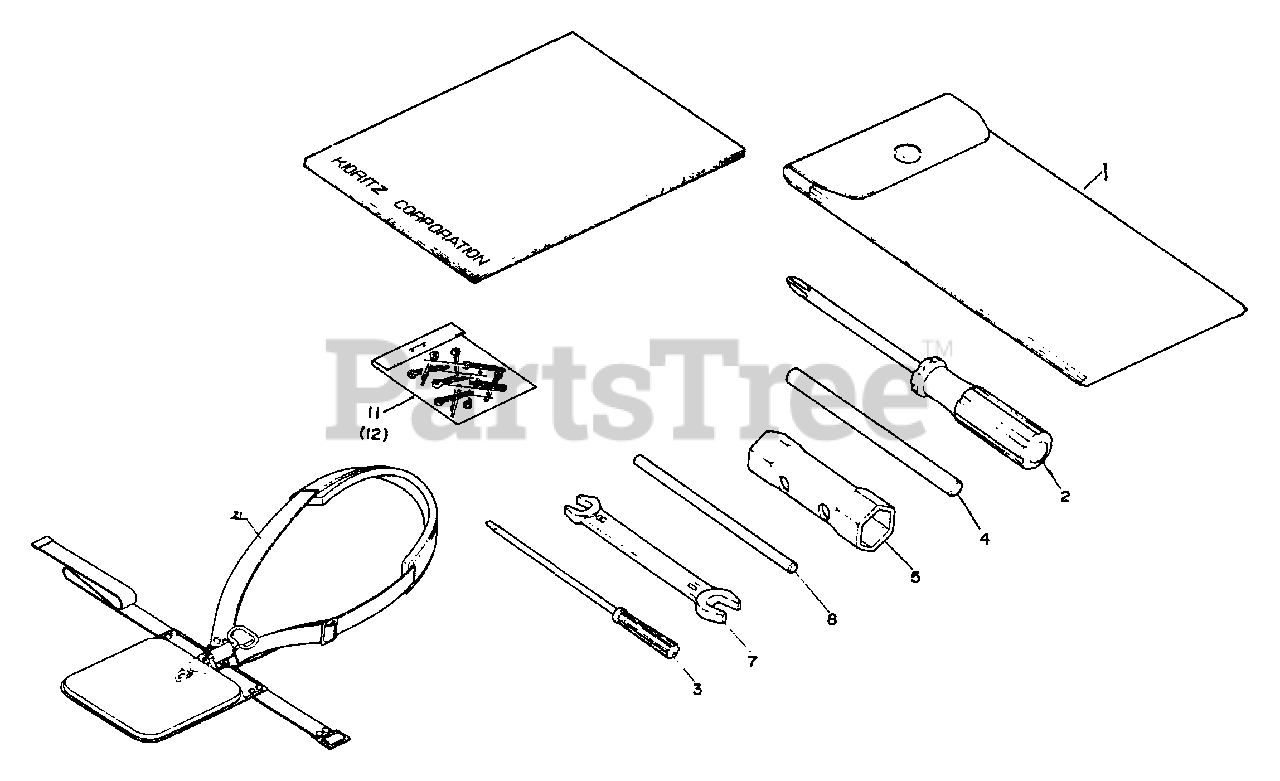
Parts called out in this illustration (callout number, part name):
1	BAG, TOOL
2	SCREWDRIVER - CROSS HEAD
3	SCREWDRIVER, SLOTTED
4	ROD, HANDLE
5	WRENCH 17×19
7	SPANNER 8×10
8	TOOL, LOCKING 5×120 MM
11	PIN, COTTER 2×22 (PKG. OF 10)
13	OWNER'S MANUAL
21	SHOULDER STRAP ASSY
